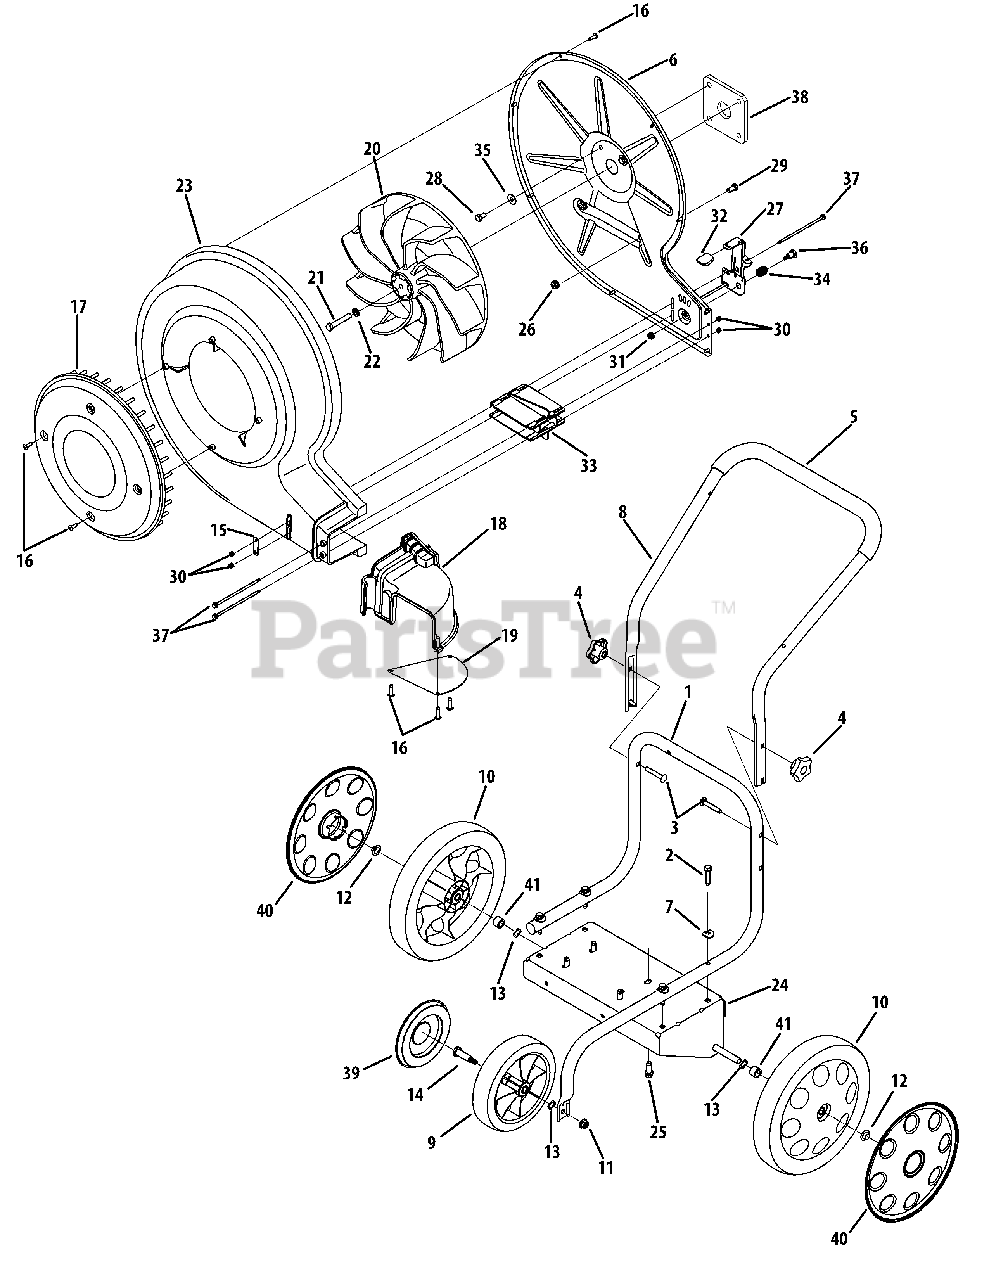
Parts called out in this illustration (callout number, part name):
1	Lower Handle Assembly
2	Hex Screw, 5/16-18 x 1.50
3	Carriage Screw, 5/16-18 x 2.00
4	Star Knob, 5/16-18
5	Foam Grip, .970 x 25
6	Back Plate
7	Saddle Washer, .320 x .93 x .060
9	Wheel, 8 x 2
10	Wheel, 12"
11	Flange Lock Nut, 3/8-16
12	Push Cap, 1/2"
13	Wave Washer, .510 x .750 x .017
14	Shoulder Screw, .498 x 1.445
16	Hex Screw, 12-16 x .75
17	Blower Cover
18	Chute Assembly
20	Impeller Assembly
21	Hex Screw, 3/8-24 x 2.25
22	Lock Washer, 3/8
23	Blower Housing
25	Sems Screw, 3/8-16 x 1.000
26	Flange Lock Nut, 5/16-18
28	Hex Bolt, 5/16-24 x .625 (205 CC)
28	Hex Bolt, 5/16-24 x 1.00 (208 CC)
29	Hex Bolt, 5/16-18 x .75
30	Hex Lock Nut, #8-32
31	Flange Lock Nut, 1/4-20
32	Height Adjustment Knob
33	Louver Plate
34	Comp. Spring, .515 x .641 x .95
35	Bell Washer, .340 x .872 x .060
36	Shoulder Screw, .437 x .50 x 1/4-20
37	Shoulder Screw, .18 x 4.8 x 8-32
38	Engine Plate (208 CC)
39	Hubcap, 8"
40	Hubcap, 12"
41	Spacer, .525 x .775 x .560
